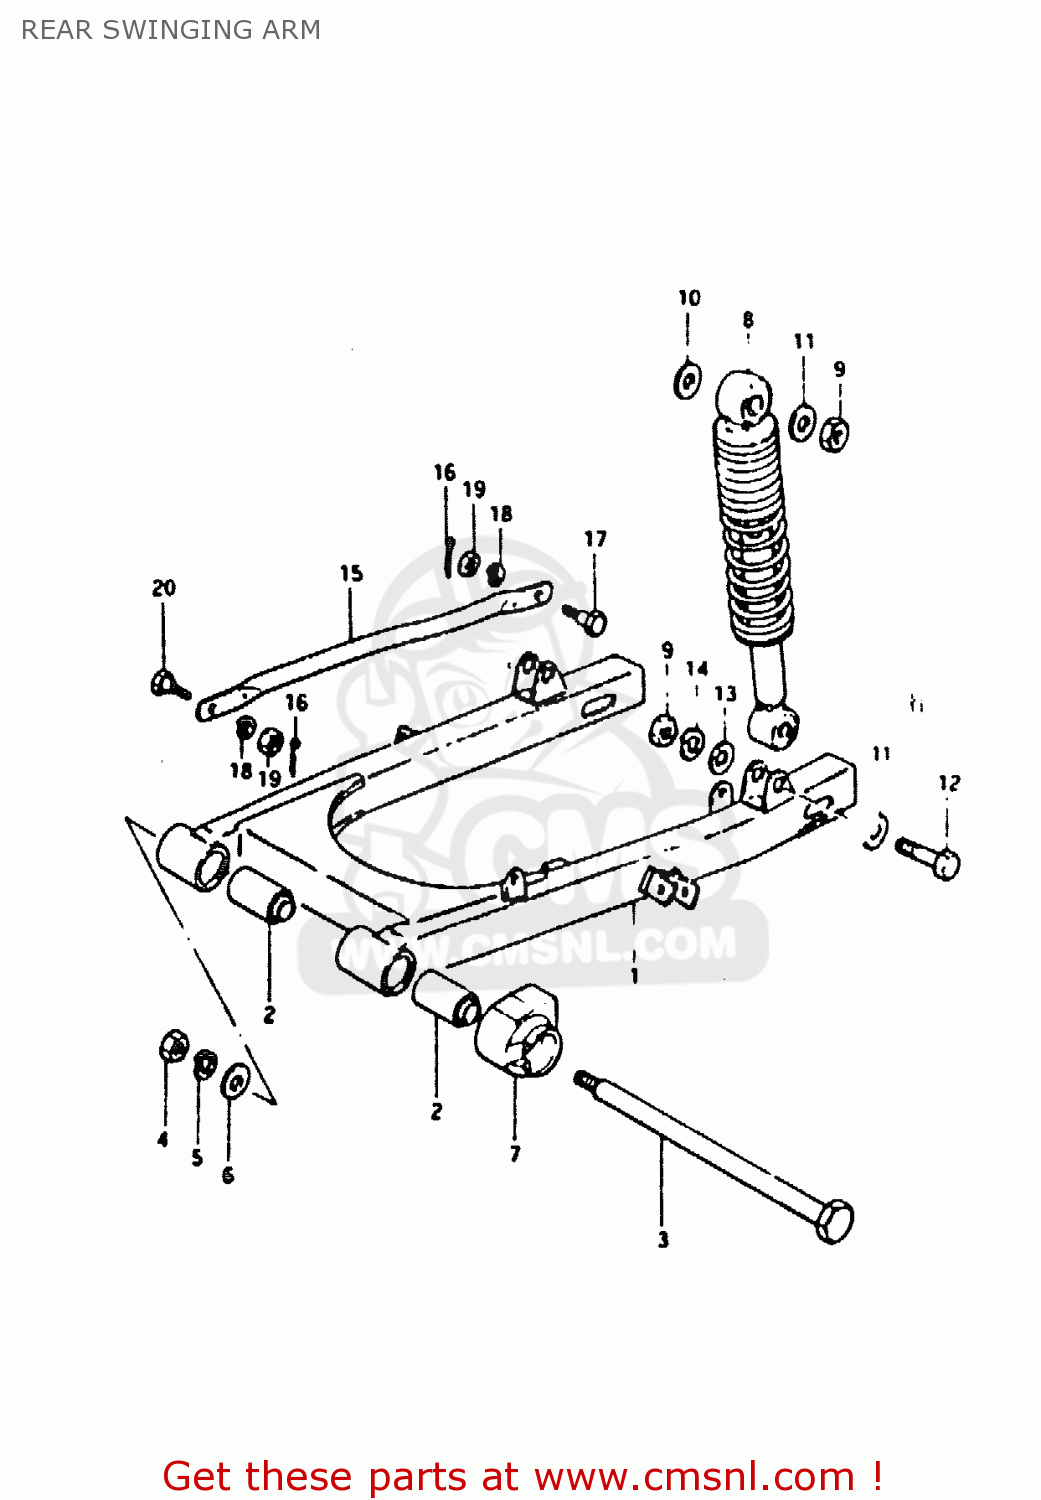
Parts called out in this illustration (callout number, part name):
1	SWINGING ARM, REAR
2	BUSH
3	SHAFT,REAR SWING ARM
4	NUT
5	LOCK WASHER
6	WASHER
7	BUFFER
8	SHOCK ABSORBER, REAR
9	NUT
10	WASHER
11	WASHER
12	BOLT(10X36)
13	WASHER
14	LOCK WASHER
15	TORQUE LINK, REAR
16	PIN 20X20
17	BOLT(8X26.5)
18	LOCK WASHER
19	NUT
20	BOLT(8X22)
